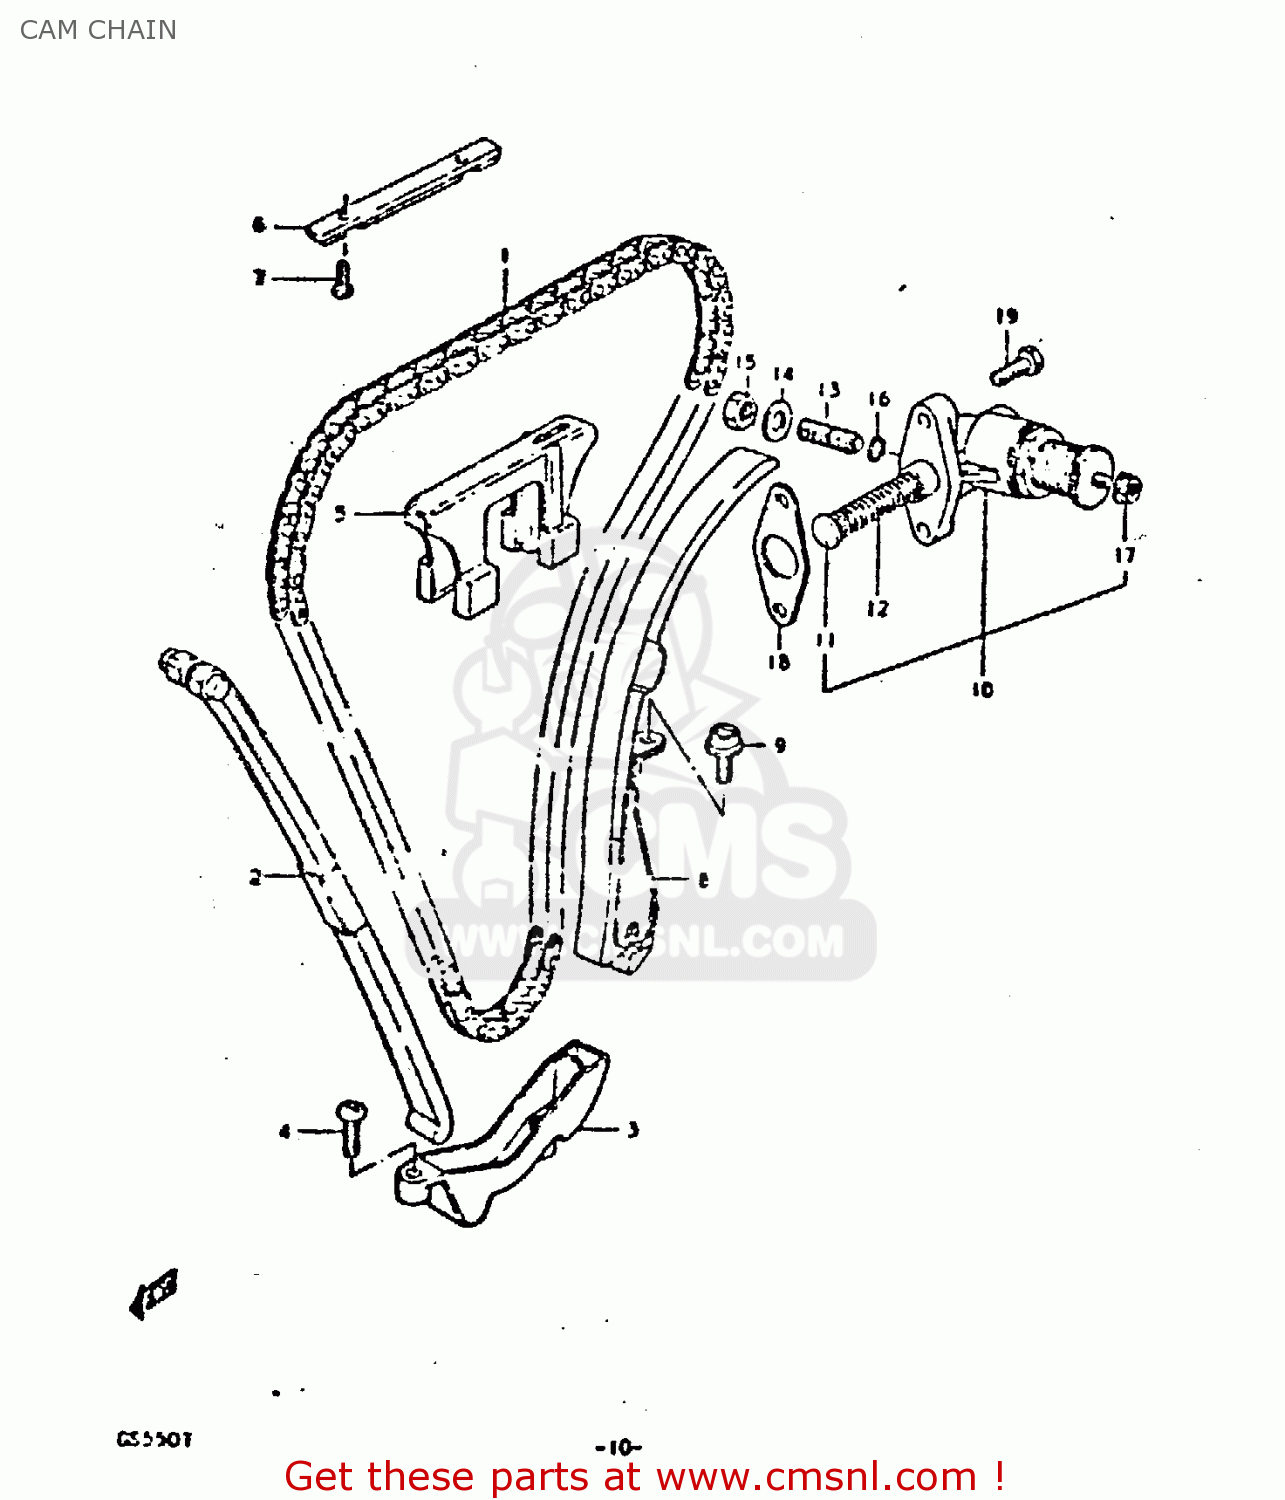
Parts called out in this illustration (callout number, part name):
1	CHAIN,CAMSHAFT DRIVE
2	GUIDE,CAM CHAIN NO.1
3	HOLDER,CAM CHAIN GUIDE
4	SCREW
5	GUIDE,CAM CHAIN NO.2
6	GUIDE,CAM CHAIN NO.3
7	SCREW
8	TENSIONER,CAM CHAIN
9	BOLT
10	ADJUSTER ASSEMBLY,TENSIONER
11	ROD,PUSH
12	SPRING
13	SCREW
14	WASHER
15	NUT
16	O-RING
17	NUT
18	GASKET,TENSIONER ADJUSTER (MCA)
19	SCREW (6X25)
